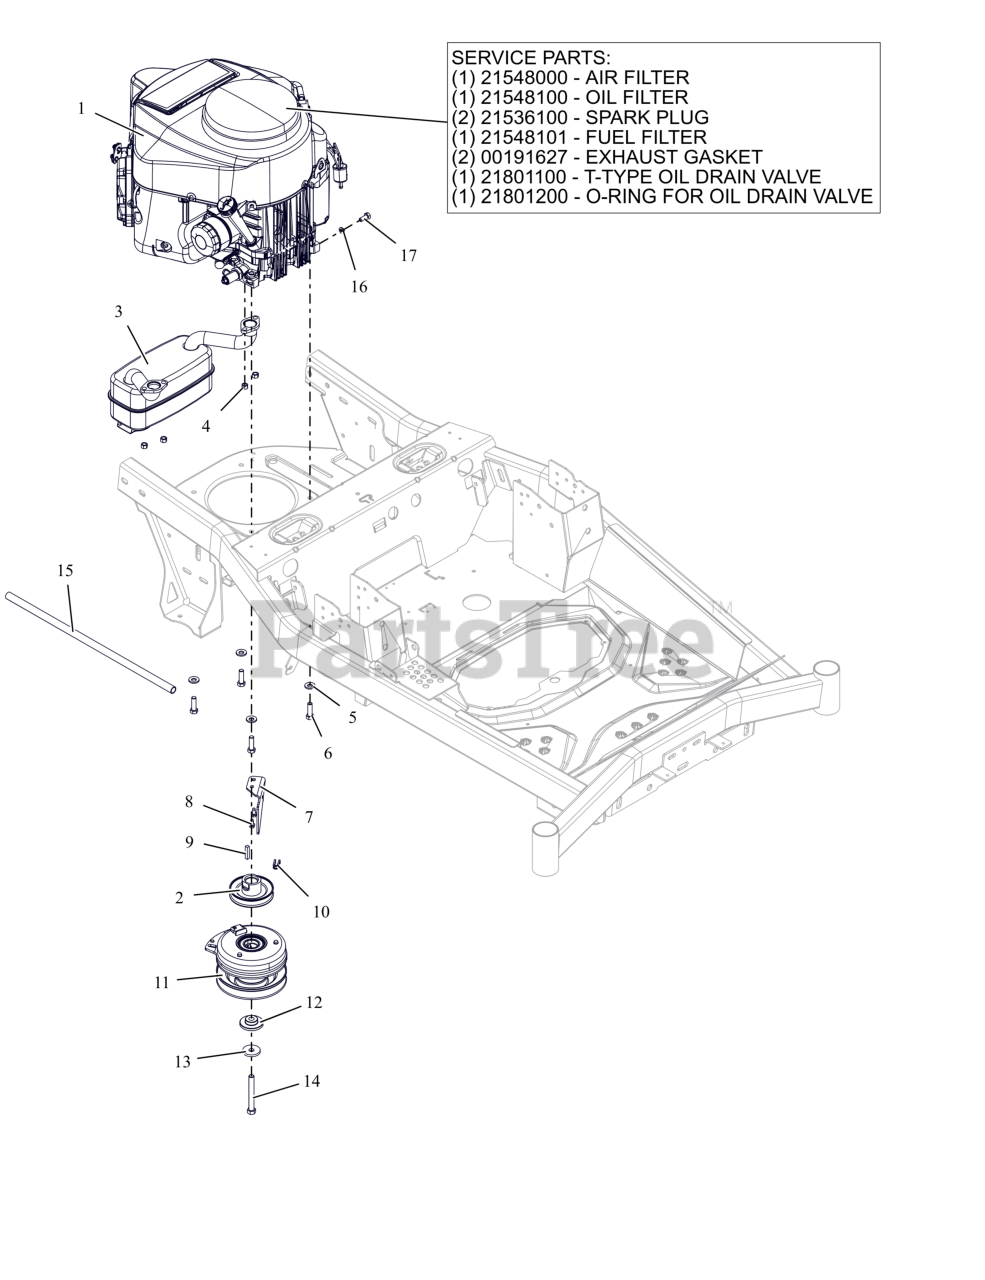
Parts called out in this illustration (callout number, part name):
1	ENGINE, KAWASAKI FR730 24HP
1	AIR FILTER, KAWASAKI FR
1	OIL FILTER, KAWASAKI FR
1	PLUG, SPARK
1	FUEL FILTER-KAWASAKI FR
1	GASKET, MUFFLER S/O
1	VALVE- T-TYPE OIL DRAIN
1	O-RING- OIL DRAIN VALVE
2	WLDMT-PULLEY-4.831OD X1.003
3	MUFFLER - KAWASAKI
4	NUT-LK-TOP-FLG M8 ZCC
5	WASHER, 3/8" SPRING DISC
6	BLT, HEX .38-16X1.25 G5 ZCC NT
7	BRKT- CLUTCH STOP
8	SCR-TAP .25-20X.50 HWH ZCC
9	KEY-SQ .25 X 1.25 X .25 SAE
10	BSHG, CLUTCH
11	CLUTCH, WARNER-IXR-18211
12	BSHG-FLG .469X1.06X.574X2.0
13	WASHER, 7/16" SPRING DISK
14	BLT- HEX .44-20X3.50 G8 ZCC NT
15	HOSE- OIL DRAIN
16	WSHR,LK-REG .312X.078 ZCC
17	BLT, HEX M8-1.25X20 G8.8 ZCC
